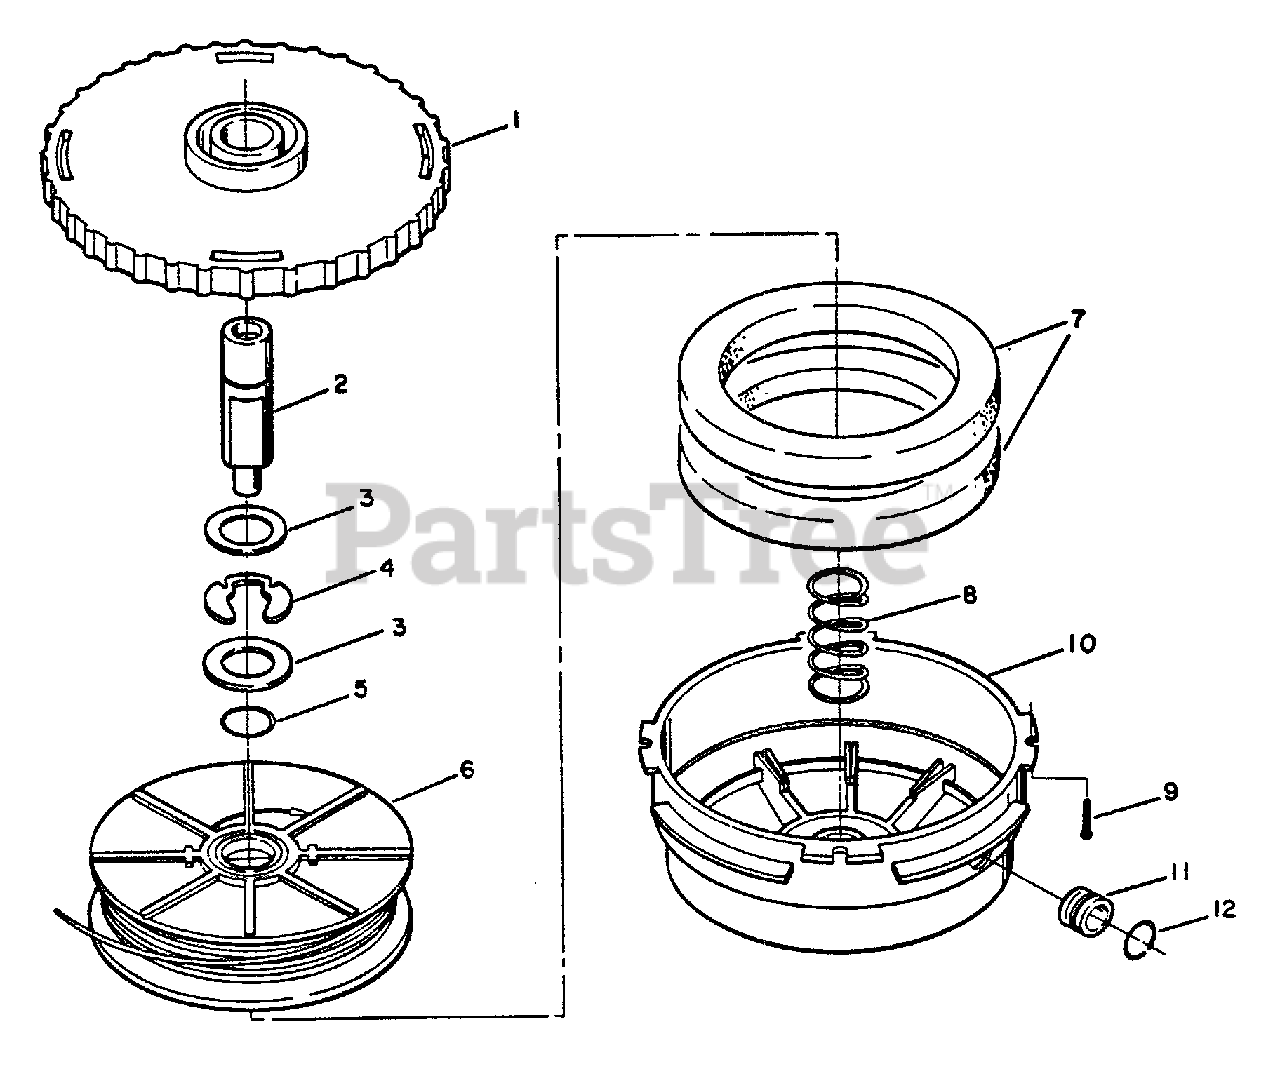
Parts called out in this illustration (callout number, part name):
1	PLATE - REAR
2	ADAPTER, DRIVE
3	WASHER
4	RING, WIRE RETAINING
5	RING, THRUST RETAINING
6	SPOOL ASSY
6	SPOOL WITH 0.080 LINE - ORANGE
6	SPOOL WITH 0.095 LINE (CLEAR)
6	SPOOL WITH 0.080 LINE (CLEAR)
7	PAD, FOAM
8	SPRING
9	PIN - COTTER
10	HUB ASSY
11	EYELET
12	RING, EYELET
